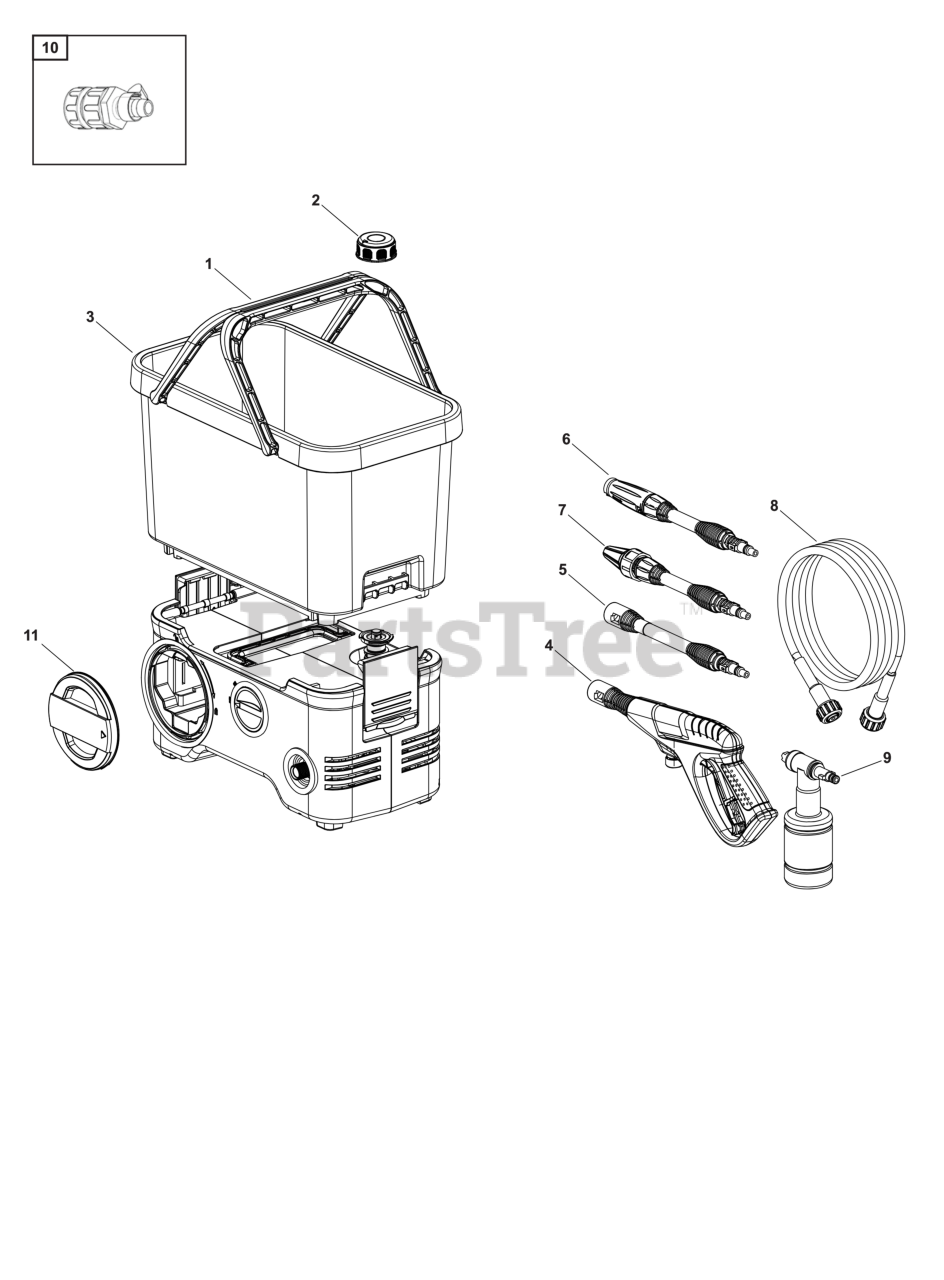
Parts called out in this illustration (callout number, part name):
1	HANDLE, BUCKET PRESSURE WASHER
2	FILTER, BUCKET
3	SNAPPER WATER BUCKET ASSY
4	BUCKET PRESSURE WASHER SPRAY GUN
5	WAND EXTENSION
6	WAND & TIP ASSY
7	WAND & ROTO TIP ASSY
8	HOSE, PRESSURE WASHER, 5M
9	DETERGENT BOTTLE ASSY
10	MAIN WATER SUPPLY CONNECTOR KIT
11	BATTERY COMPARTMENT COVER C
